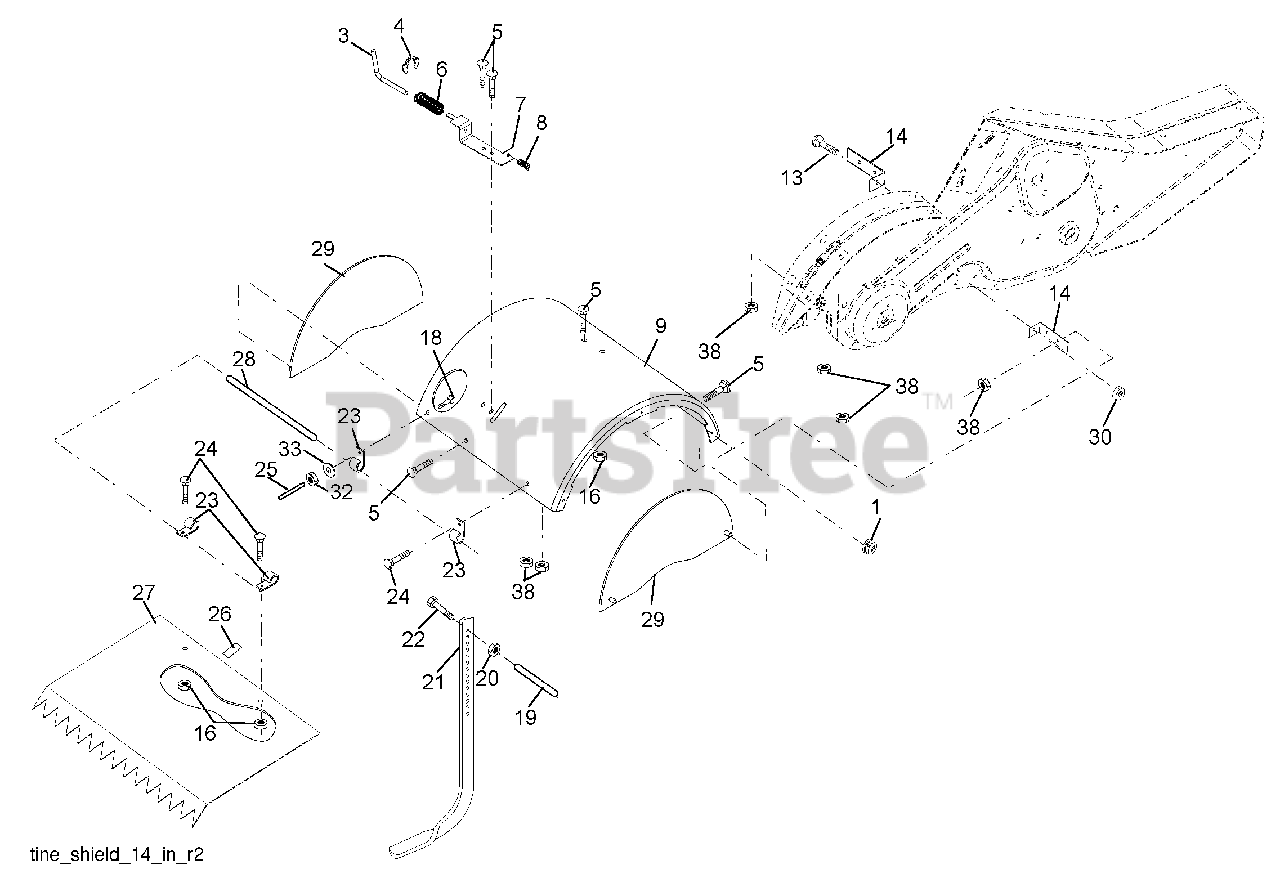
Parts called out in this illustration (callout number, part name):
1	Nut, Lock Hex Flange 5/16-18
3	Pin, Stake, Depth
4	Ring, Klip
5	Bolt, Rdhd Sqnk 5/16-18 x 3/4
7	Bracket, Latch
8	Spring, Depth Stake
9	Shield, Tine
13	Bolt, Carriage 5/16-18 x 1-1/4
14	Bracket, Shield Tine
16	Nut, Hex Flange 1/4-20 unc
18	Bolt, Carriage 1/4-20 x 1-1/4 Gr.
20	Nut, Hex 3/8-16
21	Stake, Depth
22	Bolt, Hex 3/8-16 x 2
24	Bolt, Carriage 1/4-20 x 1/2 Gr. 5
25	Cap, Vinyl
26	Pad, Idler
27	Shield, Leveling
28	Pin, Hinge
29	Shield, Side
30	Nut Lock Hex Flange
32	Nut Fin Hex 1/4-20 unc
33	Washer Lock Hvy Helical 1/4
38	Nut, Keps Hex 5/16-18 unc
